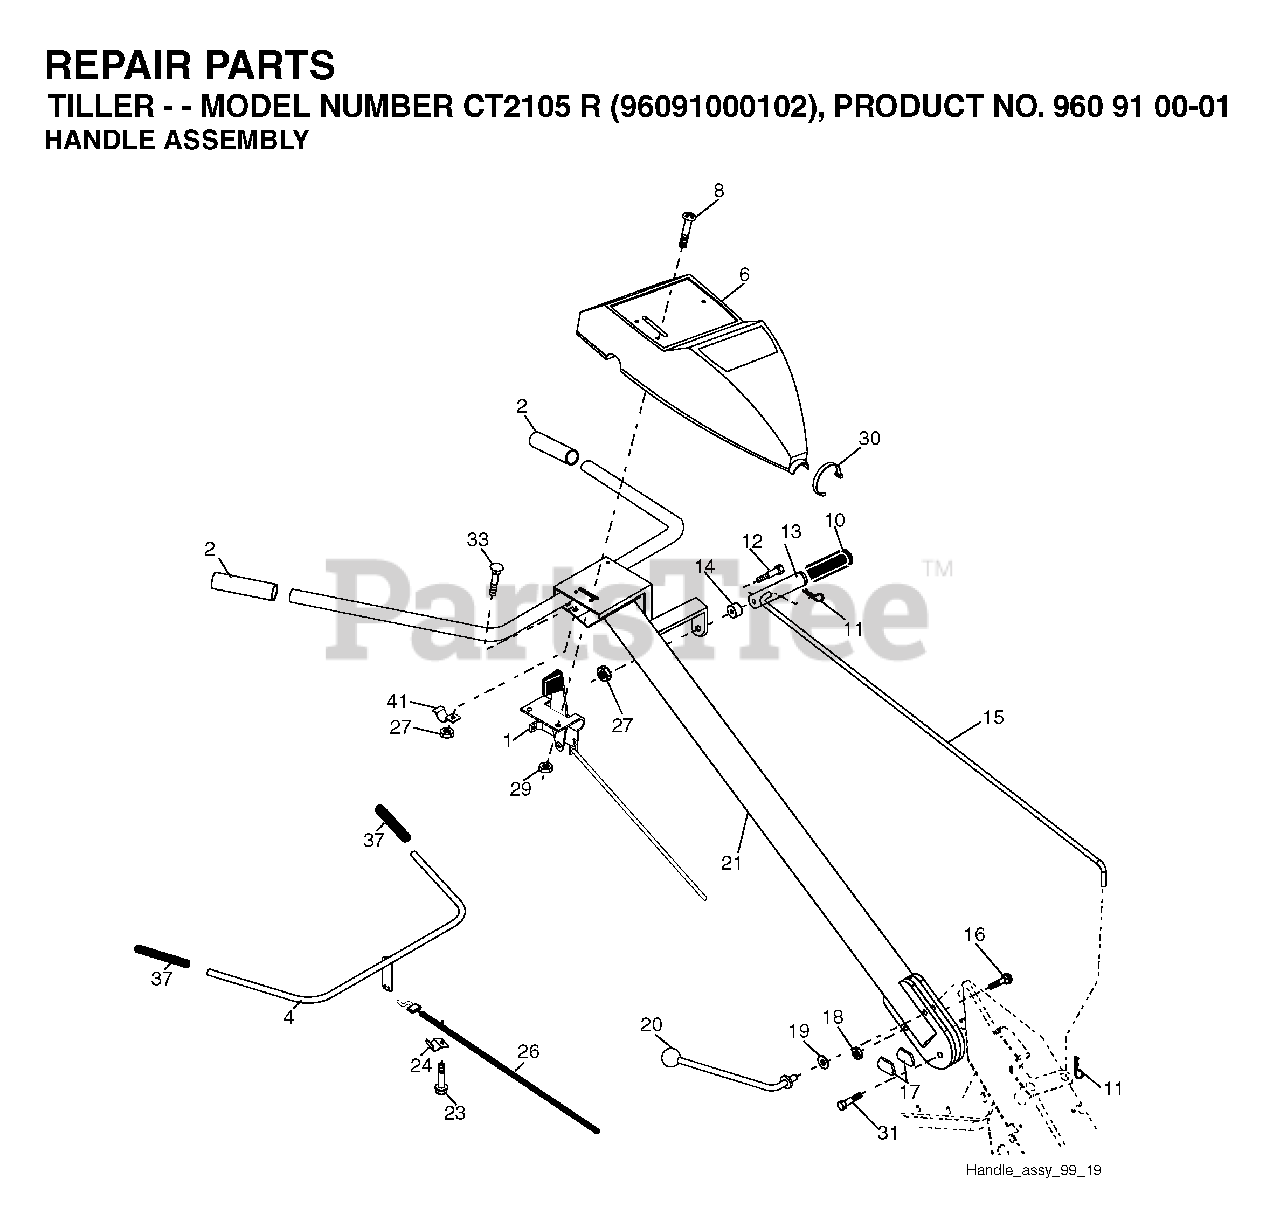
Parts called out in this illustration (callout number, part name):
1	THROTTLE.CONTROL.RT
2	GRIPS (2EACH)
4	CONTROL BAR ASSY
8	SCREW.PNHD.10-24
10	GRIP T
11	RETAINER M
12	SHOULDER BOLT ST
13	HANDLE.SHIFT.TILLER
14	GROMMET.RUBBER.CRT.TILLER
15	SHIFT ROD CRT
18	LOCKNUT
19	WASHER CRT
20	LEVER.LOCK.CRT
23	TAPPING SCREW
24	CONDUIT CLIP T
26	CABLE.CLUTCH
27	NUT T
29	NUT **
30	TIE CABLE CRT
31	BOLT.PIVOT
33	BOLT
37	GRIP BAR CRT(1)
41	CLAMP.BAR.CRT.BLACK
